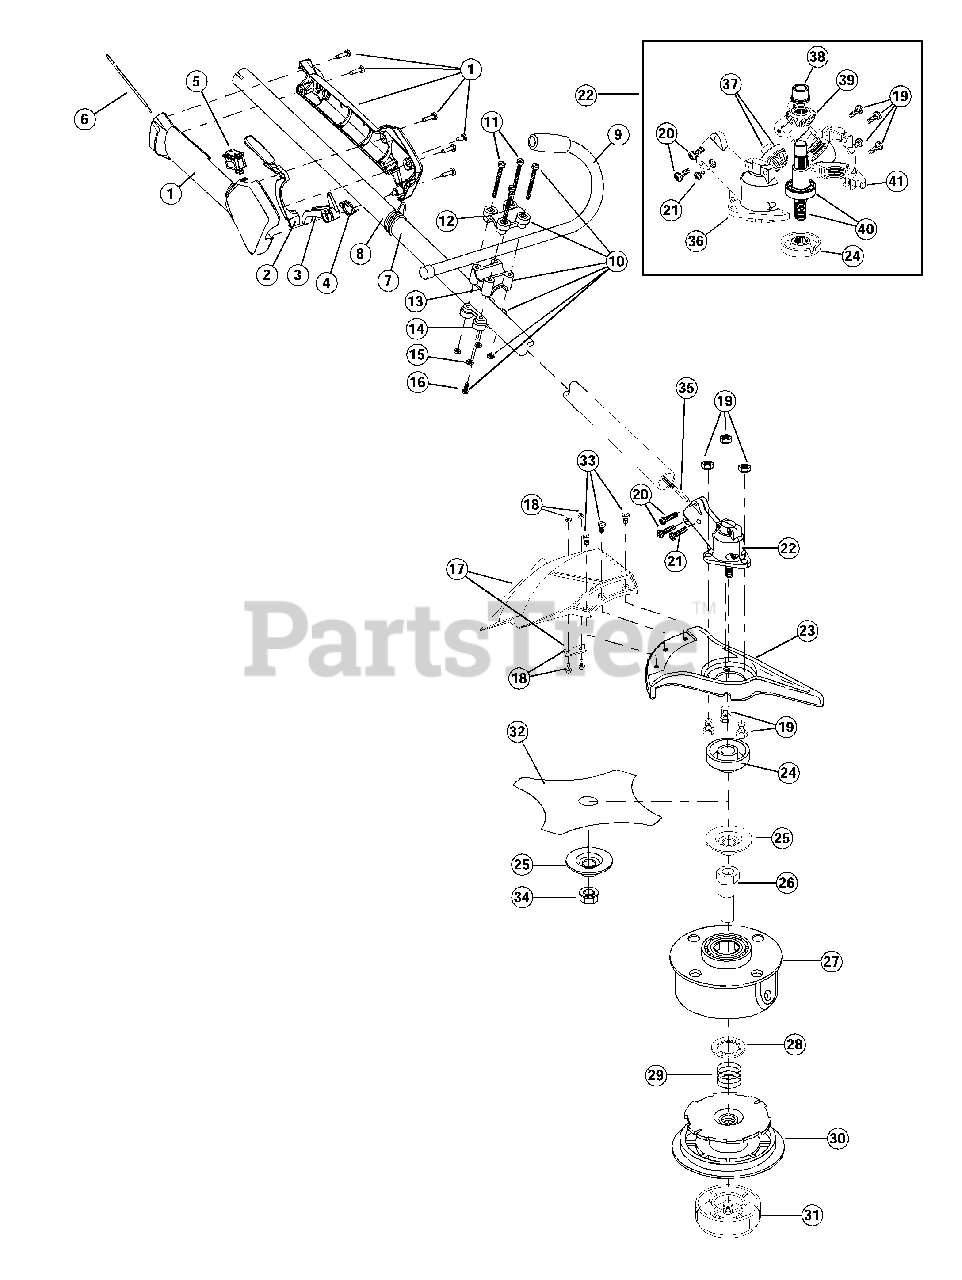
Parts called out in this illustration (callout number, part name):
1	Throttle Housing and Trigger Assembly
2	Throttle Trigger Lock-Out
3	Throttle Trigger
4	Throttle Trigger Spring
5	Switch Assembly
6	Throttle Cable Assembly
7	Harness Clip
8	Upper Drive Shaft Housing Assembly
9	J-Handle Assembly
10	Handle Bracket Assembly
12	Upper Handle Clamp
13	Middle Handle Clamp
14	Lower Handle Clamp
16	Anti-Rotation Screw
17	Shield and Blade Assembly
18	Blade Assembly
19	Shield Mount Screw Assembly
20	Gearbox Mounting Hardware
21	Anti-Rotation Screw
22	Gearbox Assembly
23	Blade Shield
24	Blade Driver
25	Retaining Washer
26	Spool Shaft
27	Outer Spool and Eyelet Assembly
28	Retainer
29	Spring
30	Inner Reel
31	Bump Head Knob Assembly
32	4-Tooth Blade
33	Guard Mount Screws
34	Nut
35	Flexible Drive Shaft
36	Right Housing
37	Pinion Gear Assembly
38	Output Shaft Bushing
39	Output Shaft Gear
40	Output Shaft Assembly
41	Left Housing
